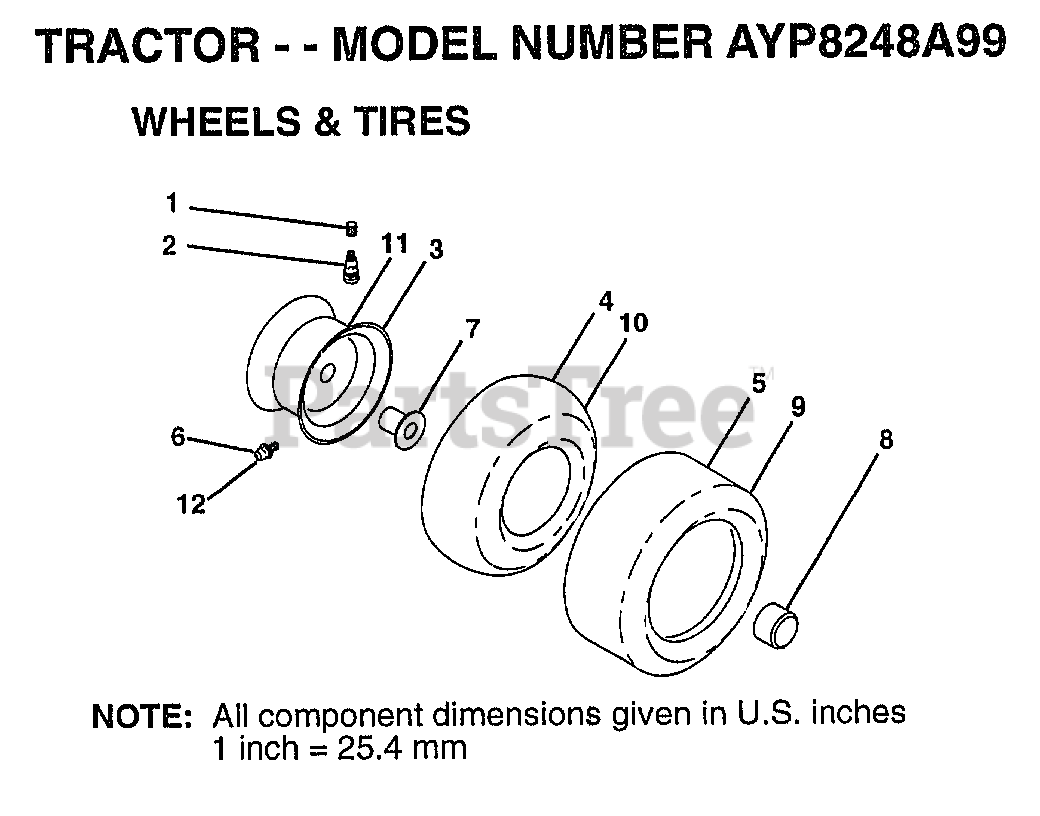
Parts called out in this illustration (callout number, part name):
1	VALVE CAP
2	VALVE STEM LT
3	"RIM ASM 8"" FRT"
4	TUBE.16X6.5/7.5-8
6	FITTING LT
7	"FLANGE, BEARING"
8	HUB CAP
10	TUBE.23X8/10-12
11	"RIM ASM 12"" REAR"
12	ZERK FITTING M
